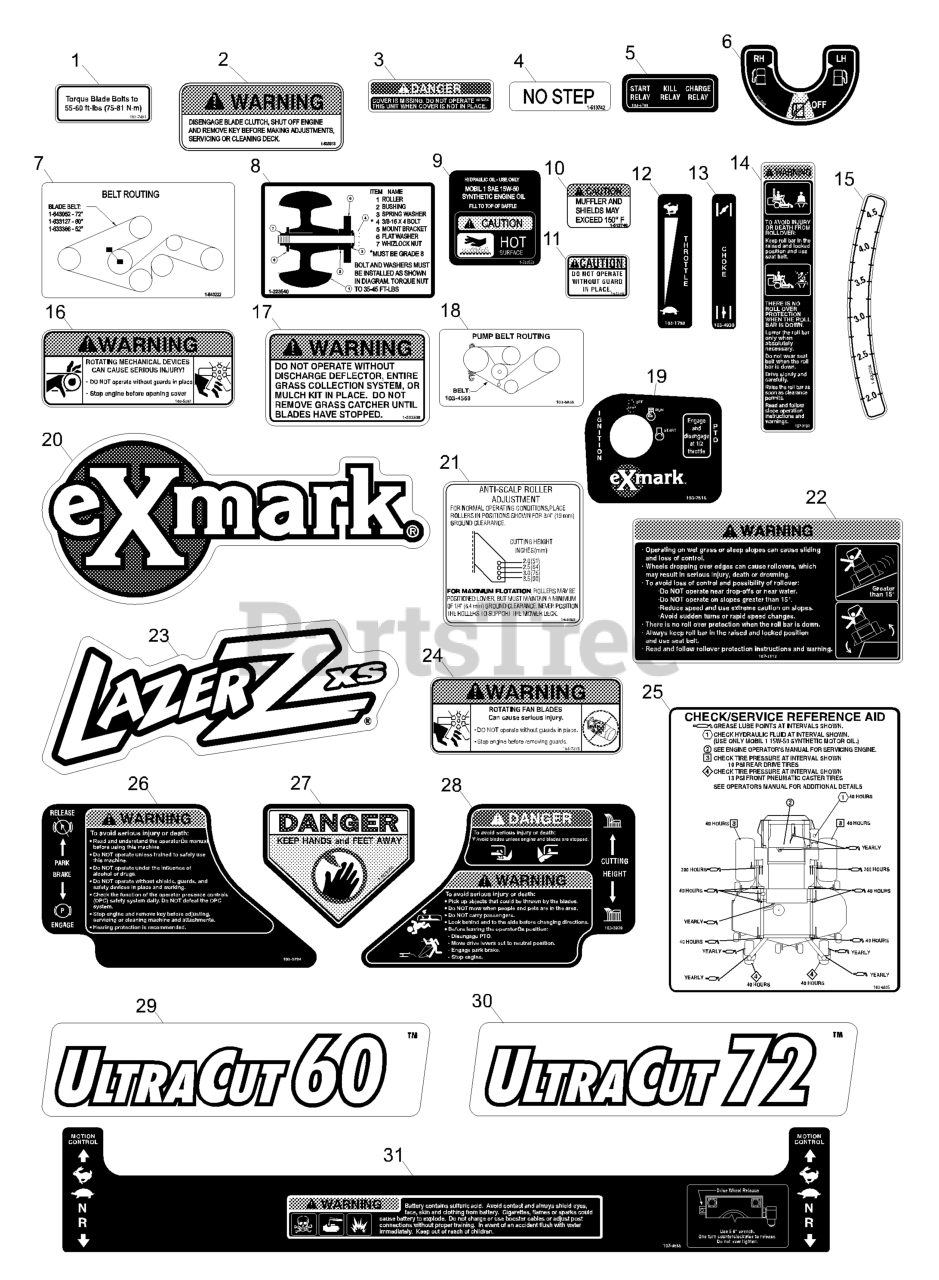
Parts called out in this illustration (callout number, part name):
2	DECAL,WARNING
3	DECAL-COVER, MISSING
4	DECAL,NO STEP
5	DECAL,RELAY
6	DECAL-VALVE, FUEL
8	DECAL,BELT ROUTING
9	DECAL,ROLLER MOUNTING
11	DECAL-GUARD
12	DECAL,THROTTLE ONLY
13	DECAL,CHOKE
14	DECAL-WARNING, FOLDING RO
15	DECAL-HEIGHT, DECK
16	DECAL-DEVICES, ROTATING
17	DECAL-WARNING, DISCHARGE
18	DECAL,PUMP BELT ROUTING
20	DECAL,EXMARK LOGO
21	DECAL,ANTISCALP
22	DECAL-WARNING
23	DECAL,LAZER XS MODEL
24	DECAL,PUMP FAN WARNING
26	DECAL,PARK BRAKE
27	DECAL-DANGER
28	DECAL,CUTTING HEIGHT
29	DECAL,ULTRACUT 60
30	DECAL,ULTRACUT 72
31	DECAL-CONSOLE, TOP
